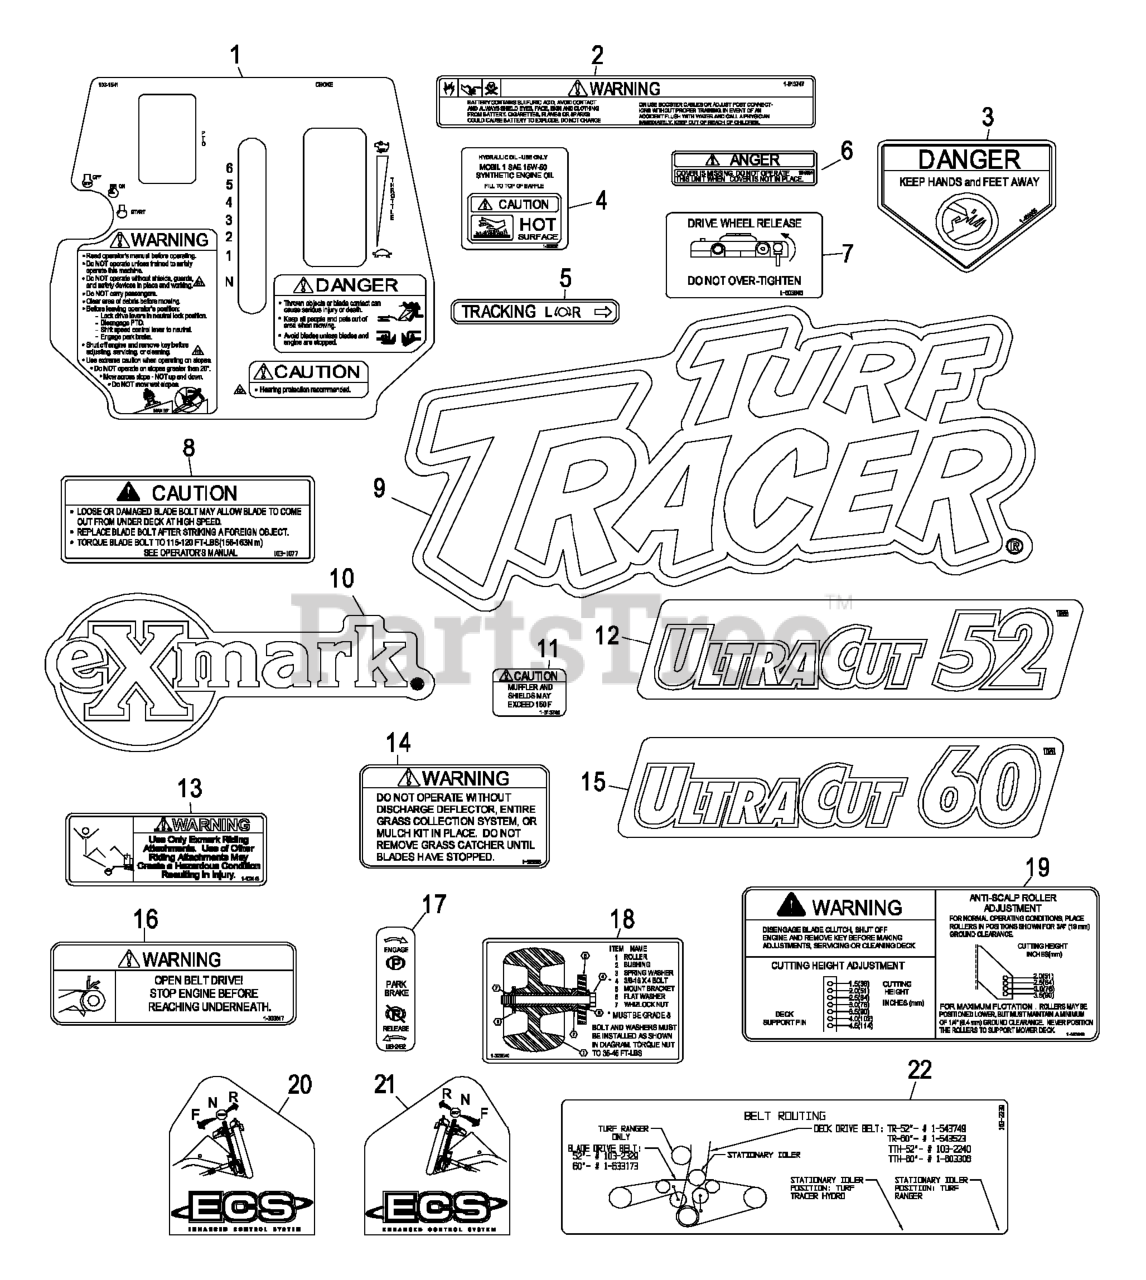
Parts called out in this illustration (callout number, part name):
1	DECAL,TTH ECS CONSOLE
2	DECAL-BATTERY
3	DECAL-DANGER
5	DECAL,TRACKING ADJUST
6	DECAL-COVER, MISSING
7	DECAL,DRIVE RELEASE
8	DECAL,BOLT TORQUE
9	DECAL,TTH MODEL
10	DECAL,EXMARK LOGO
12	DECAL,ULTRACUT 52
13	DECAL,SULKY WARNING
14	DECAL-WARNING, DISCHARGE
15	DECAL,ULTRACUT 60
16	DECAL,BELT DRIVE
17	DECAL,PARKING BRAKE
18	DECAL,ROLLER MOUNTING
19	DECAL,ANTI SCALP
20	DECAL,LH ECS INSTRUCTION
21	DECAL,RH ECS INSTRUCTION
22	DECAL,BELT ROUTING
